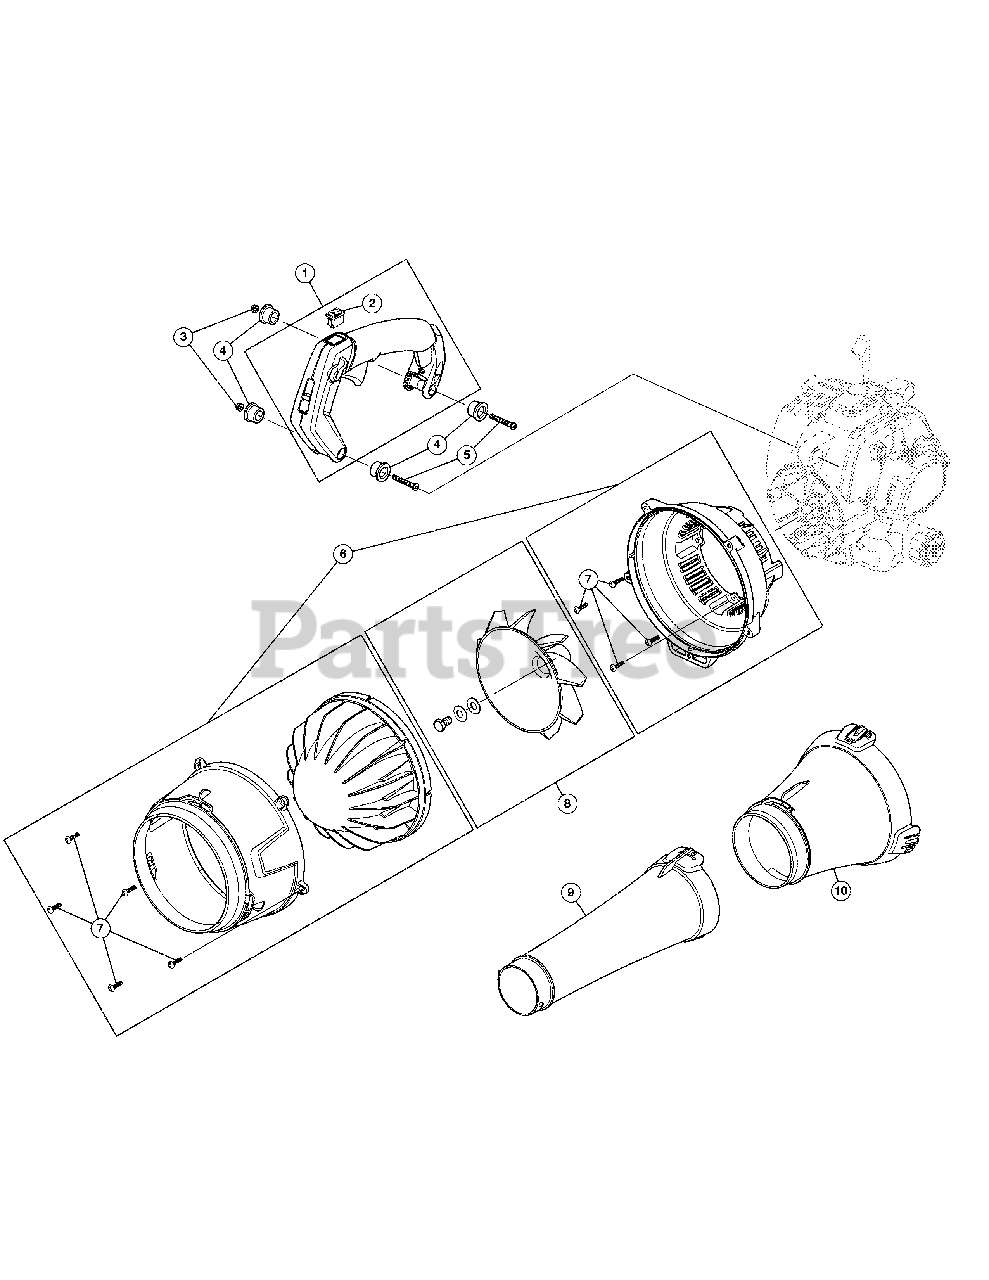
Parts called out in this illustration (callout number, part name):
1	Handle Assembly
4	Isolator (x4)
5	Screw (x2)
6	Fan Housing Assembly
7	Screw (x9)
8	Fan Assembly
10	Upper Tube
